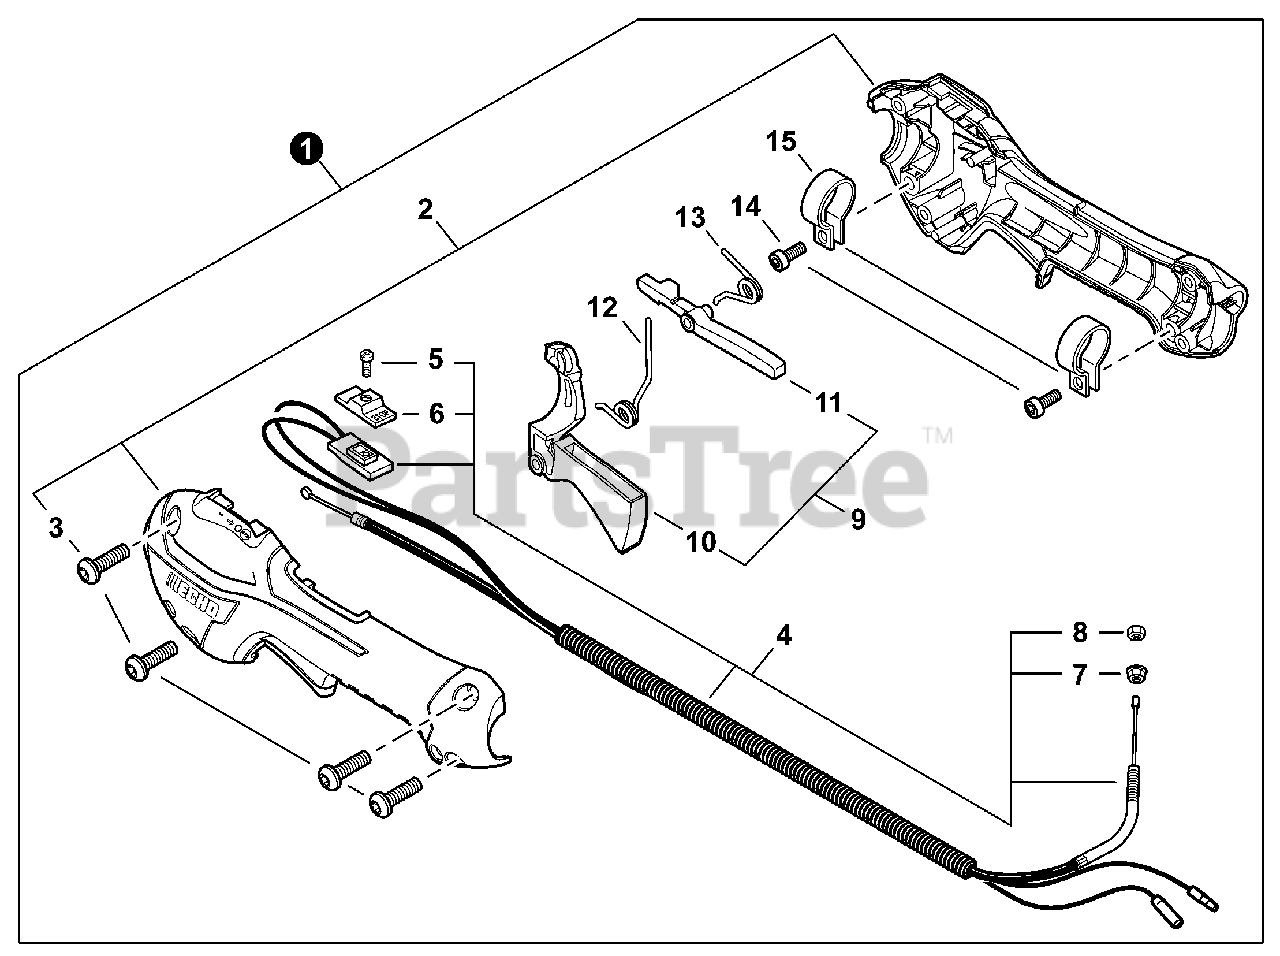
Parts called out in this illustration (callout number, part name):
1	CONTROL HANDLE ASSY
2	CONTROL HANDLE KIT
3	BOLT, TORX 5x16
4	CABLE ASSY, CONTROL
5	SCREW 3x10
6	KNOB, SWITCH - ORANGE
7	NUT, FLANGE M6
9	THROTTLE LOCKOUT KIT
10	TRIGGER, THROTTLE
11	LEVER, THROTTLE LOCKOUT
12	SPRING, TORSION
13	SPRING, TORSION
14	BOLT, TORX 5x16
